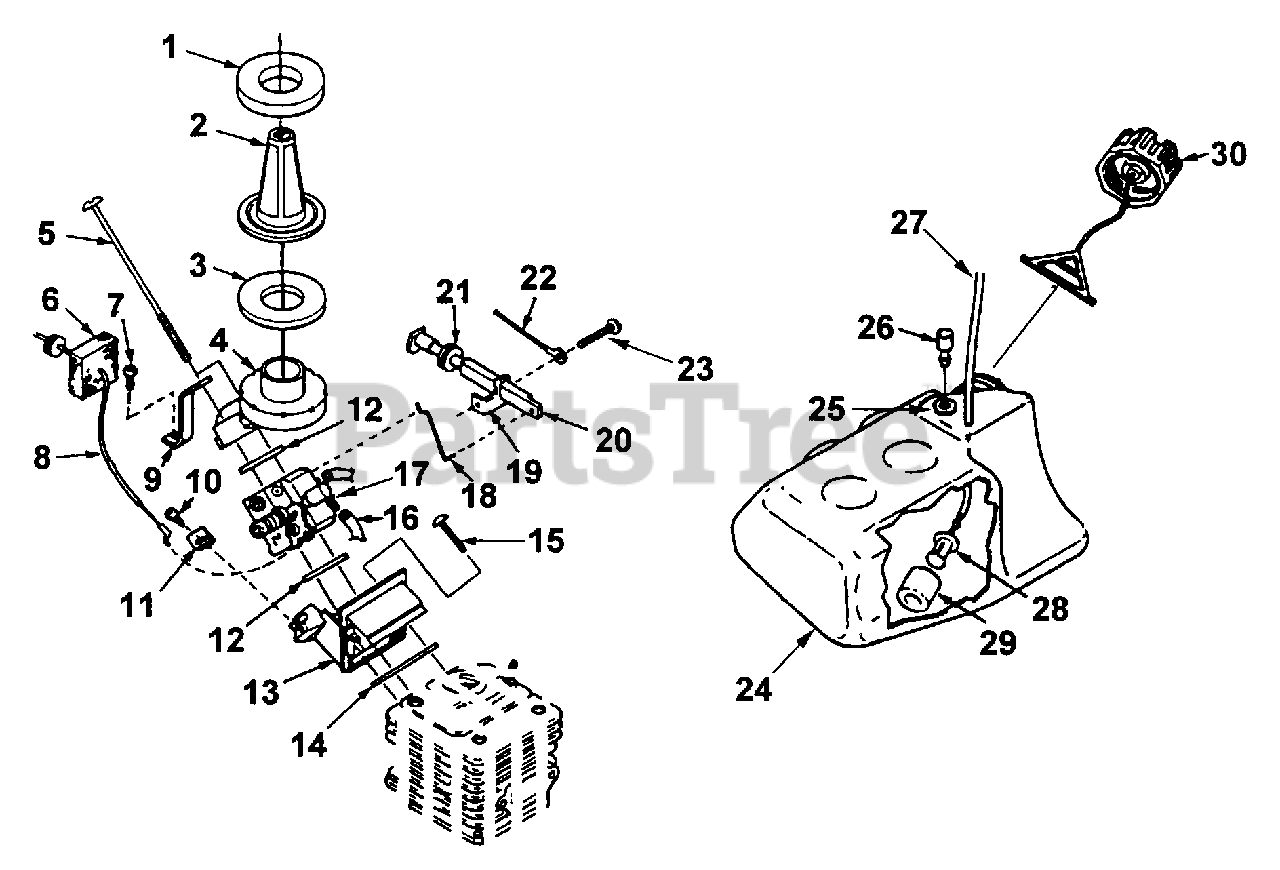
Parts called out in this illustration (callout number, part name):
1	GASKET - Foam (1/4")
2	FILTER - Screen
3	GASKET - Foam
4	ADAPTOR - Intake
5	SCREW - Truss Hd (8-16 x 3-1/4")
6	PAD - Foam
7	SCREW - Torx (10-24 x 1/2")
8	CABLE - Throttle
9	BRACKET - Air Intake
10	SCREW - Thread Form (6-19 x 1/2")
11	BRACKET - Cable End
12	GASKET - Carburetor
13	ADAPTOR - Intake
14	GASKET - Adaptor
15	SCREW - Pan Hd (10-24 x 1")
16	TUBING, Pulse line (4-3/4")
17	CARBURETOR - Walbro
18	CHOKE LINK & RETAINER
19	BRACKET - Cable
20	ROD - Choke
21	GROMMET
22	GROUND WIRE
23	SCREW - Truss Hd (10-24 x 1-1/4")
24	TANK - Fuel
25	GROMMET
26	FILTER SLEEVE
27	TUBING - Rubber (10")
28	FILTER - Fuel
29	FILTER - Fuel
30	CAP - Tank (w/Retainer)
